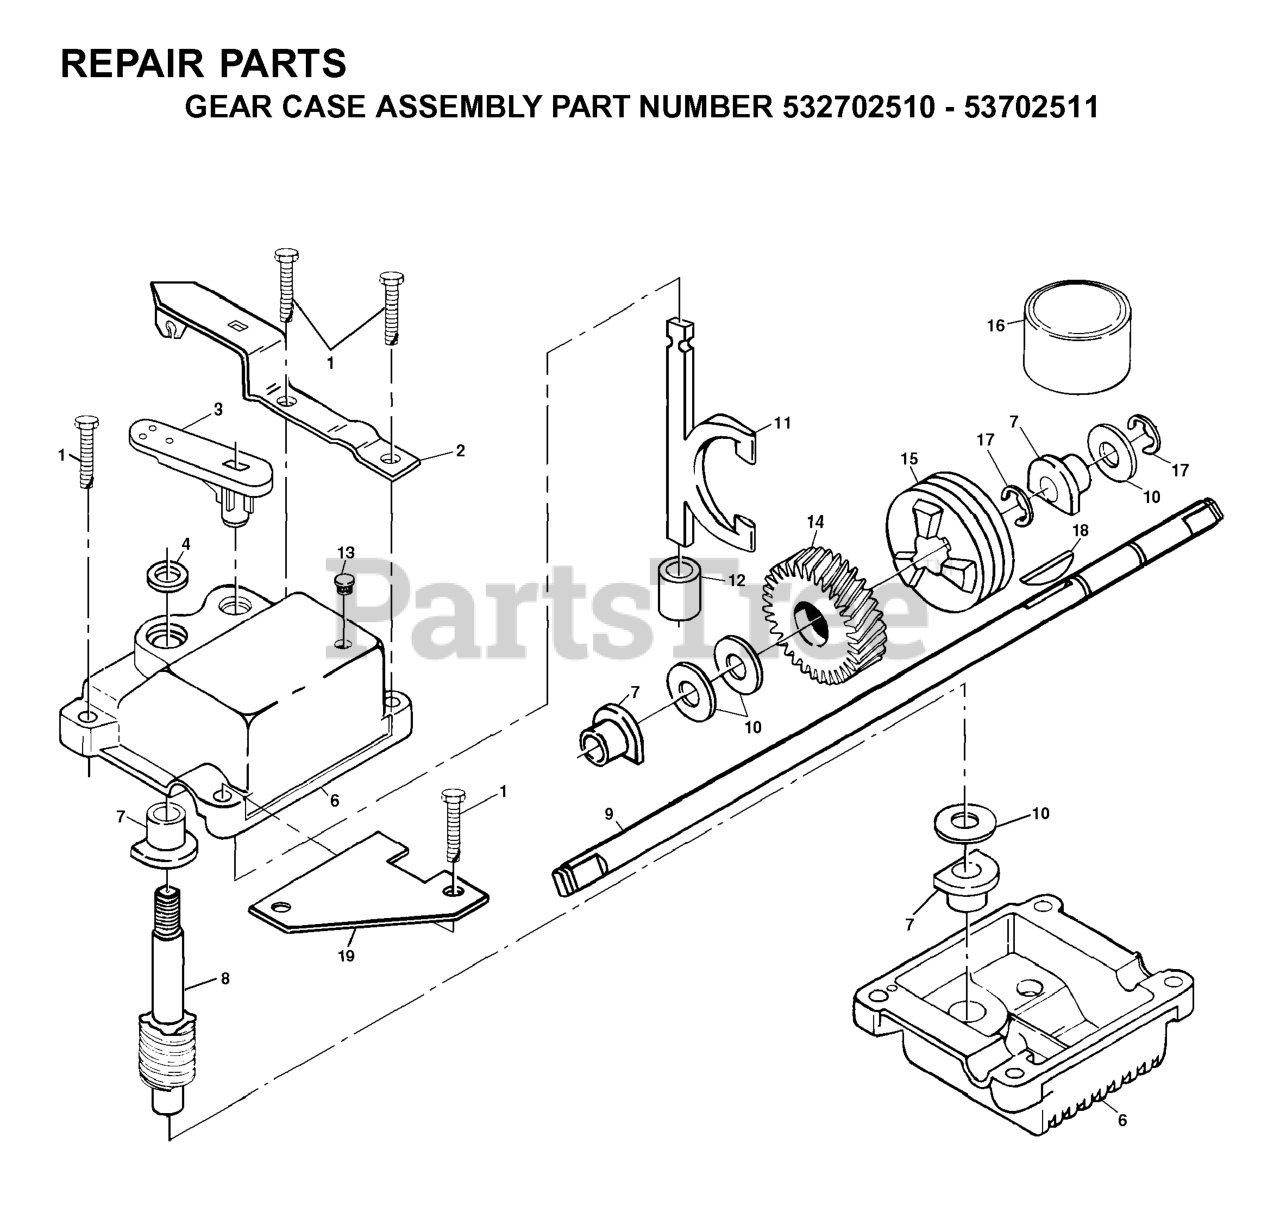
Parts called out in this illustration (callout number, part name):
1	SCREW
2	BRACKET
8	WORM SHAFT
9	DRIVE SHAFT, 20-5/8"
10	THRUST WASHER
11	YOKE.VIBRATORY FINISH.
13	PLUG.AUGER.GEAR.BOX.SNOW
14	GEAR.HELICAL
15	CLUTCH JAW
16	GREASE
18	HI PRO KEY
19	BRACKET SPRING
